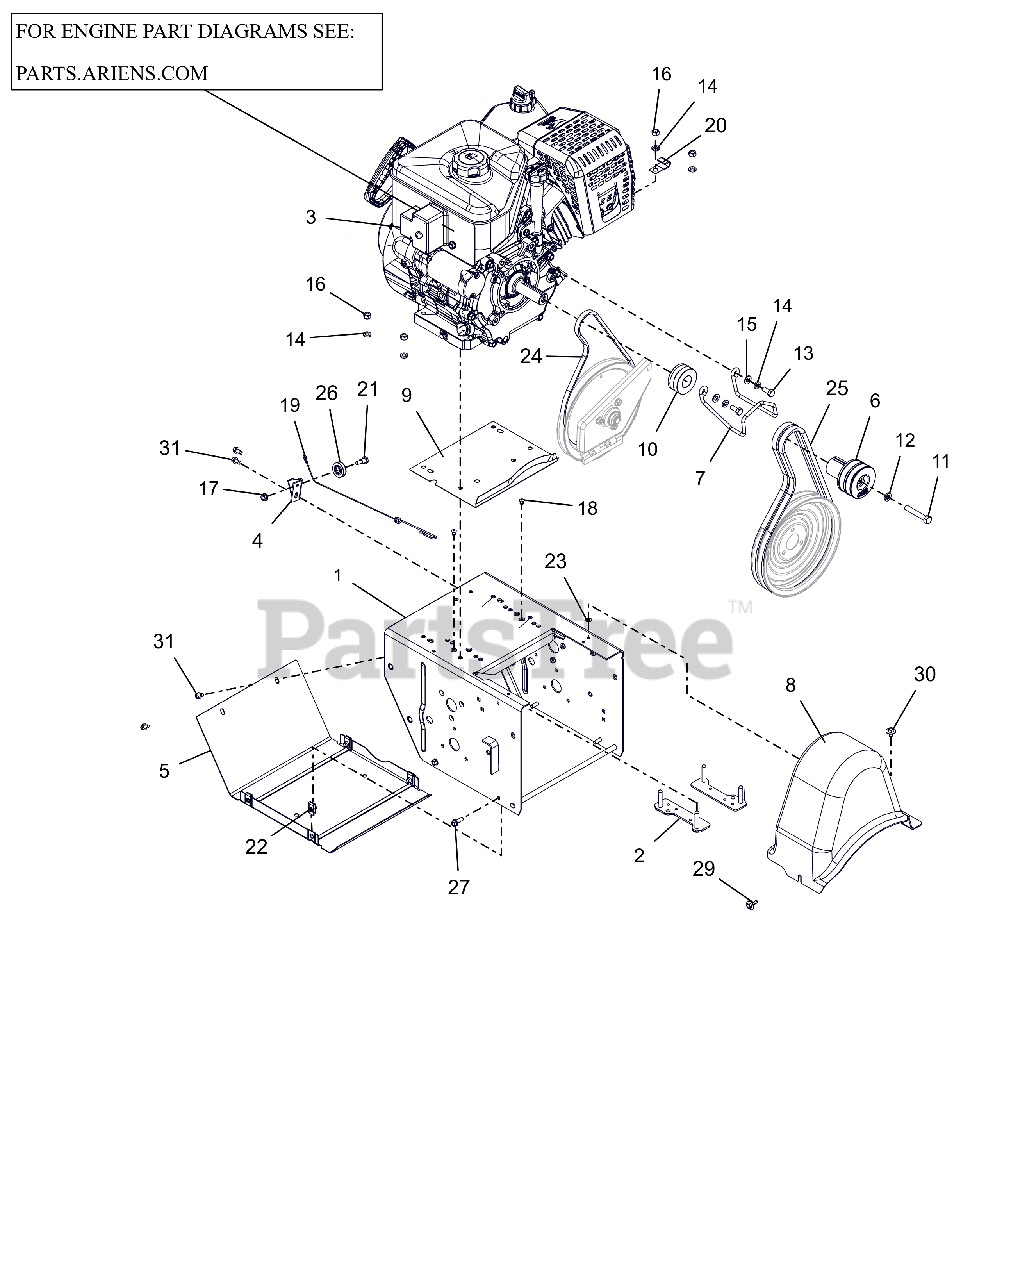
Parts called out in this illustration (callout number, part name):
1	FRAME, MAIN-DELUXE(WELDMENT)
2	STRAP, BOLT-LARGE
3	ENGINE, AX369 GEN3 120V/60W
4	BRACKET, CABLE PULLEY
5	COVER, BOTTOM
6	SHEAVE,ATTACHMENT-SHO 2 GRV
7	FINGER, BELT
8	COVER, BELT-LARGE
9	BAFFLE, WATER - LARGE BLOCK
10	SHEAVE, TRACTION (KEYLESS)
11	BLT, HEX .38-24X2.25 G5 ZCC
12	WSHR,LK-REG .375X.094 ZCC
13	BLT, HEX .31-24X.750 G5 ZCC
14	WSHR, LK-HVY .312X.097 ZCC
15	WSHR,FLT .344X.688X.065 ZCC
16	NUT, HEX .312-18 ZCC
17	NUT-LK-TOP-FLG .250-20 GF ZCC
18	RVT, POP .1875 ZCC
19	CABLE, LOWER TRACTION,SS & PRO
20	J-CLAMP
21	BOLT, SHLDR -.375 X .375 X .25-20
22	NUT-RTNR .25-20X.56
23	NUT-PUSH .25X.50 O.D.
24	V-BELT, 3L-WRAPPED
25	V-BELT, HA-RAW EDGE (SET)
26	PULLEY, CABLE
27	BLT, HWH .25-20X.75 G5 ZCC
29	SCR-TAP .25-20X.5 CAPTIVE
30	SCR, TAP .25-20X.50 LG HWH ZCC
31	SCR-TAP .25-20X.50 HWH ZCC
